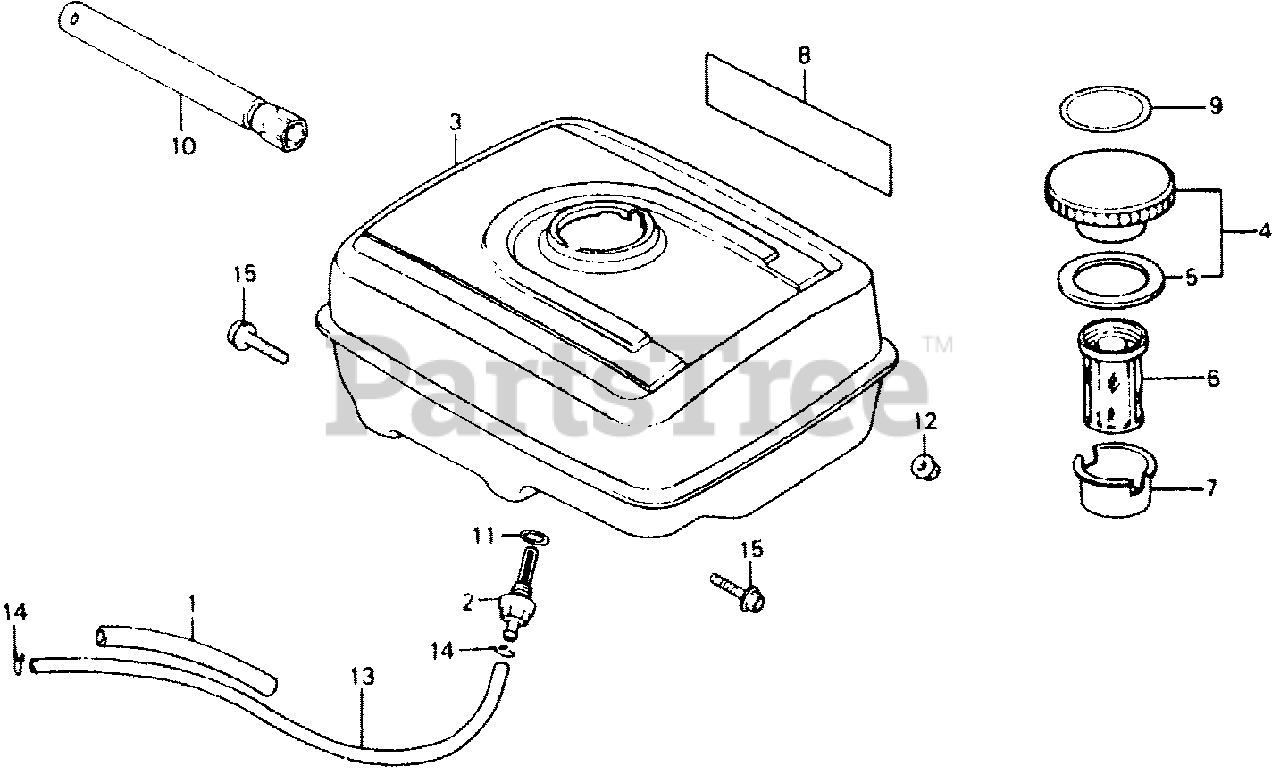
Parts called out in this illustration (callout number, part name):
1	RUBBER, SUPPORTER (107MM)
2	JOINT, FUEL TANK
3	TANK, FUEL *NH31* (MCKINLEY WHITE)
4	CAP, FUEL FILLER
5	GASKET, FUEL FILLER CAP
6	FILTER, FUEL
7	HOLDER, FUEL FILTER
8	MARK (WT30X)
9	MARK, CAUTION (EXTERNAL)
10	WRENCH, SPARK PLUG
11	O-RING (13.5X1.5) (ARAI)
12	NUT, FLANGE (8MM)
13	BULK HOSE, FUEL (4.5X3000) (4.5X222)
14	CLIP, TUBE (B8)
15	BOLT, FLANGE (8X25)
